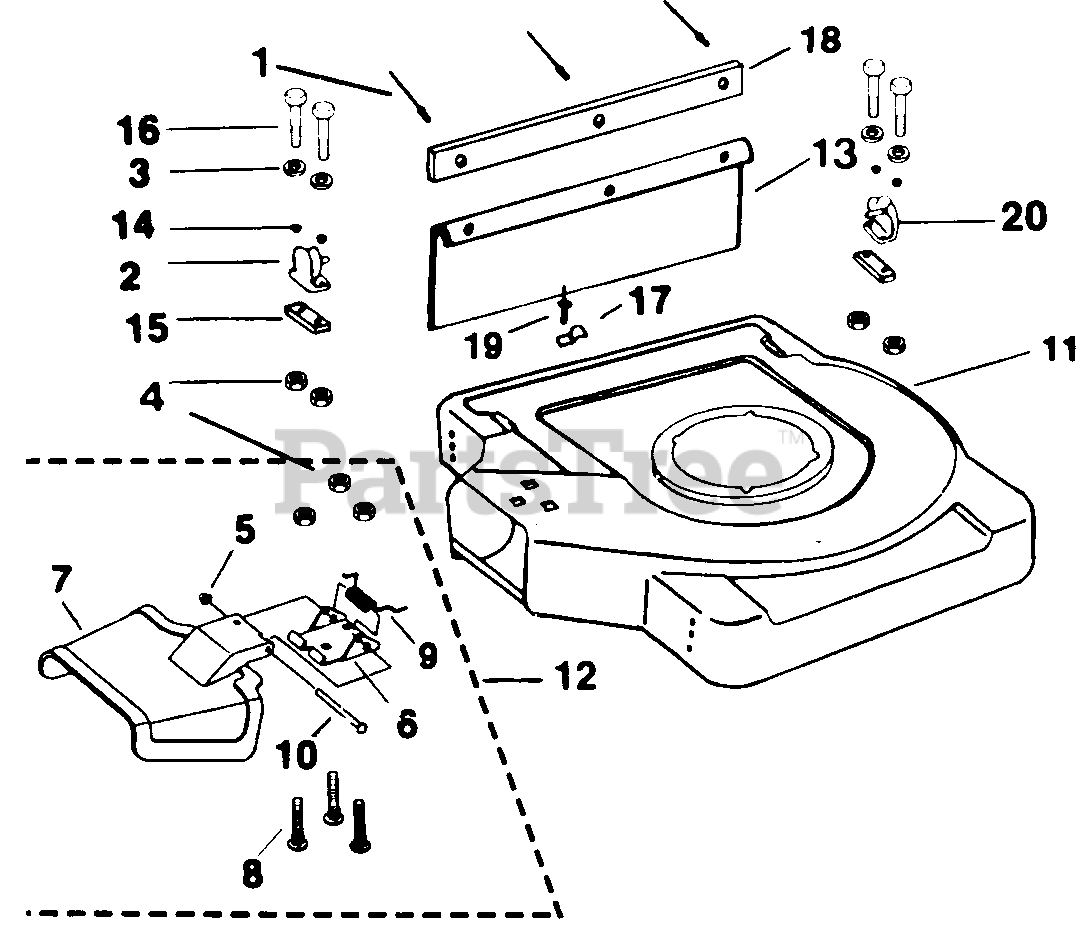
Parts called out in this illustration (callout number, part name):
1	Blind Rivet
2	llandlebar Bracket R.H.
3	1/4" Flat Washer
4	1/4" - 20 Locknut
5	Button Retainer
6	Hinge Bracket
7	Guard - Chute (Plastic)
8	1/4" - 20 x 1/2" Carriage Bolt
9	Spring
10	Hinge Pin
11	19" Deck
12	Chute Guard Ass'y. (Plastic)
13	Trail Shield
14	Insulator
15	Insulator Strip
16	1/4" - 20 x 7/8" HHCS
17	Clamp
18	Strap - Trail Shield
19	Blind Rivet
20	Handlebar Bracket L.H.
